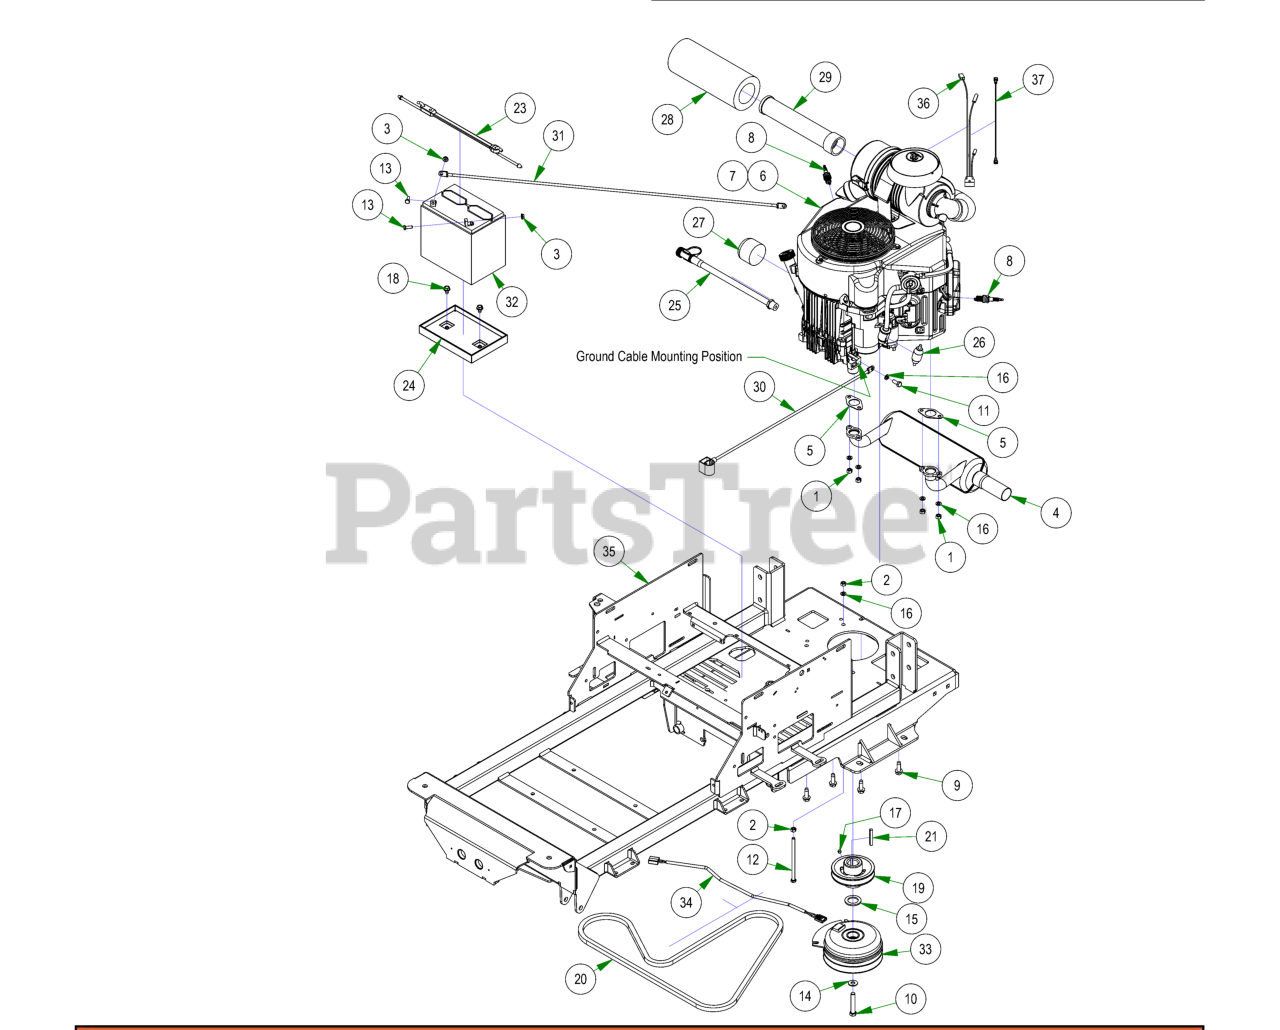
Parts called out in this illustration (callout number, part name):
1	M8-1.25 DIN 934 HEX NUT (CL.8) ZINC
2	5/16-18 HEX NUT ZINC
3	1/4-20 HEX SERRATED FLANGE NUT HARD/ZINC
4	Kawasaki Muffler 1251
5	Exhaust Gasket
6	FX691 Kawasaki-2016 Compact Outlaw
8	Spark Plug - Kawasaki
9	3/8-16 X 1-1/8 HEX WASHER UNSLOT SERRATED (TRI-LOB) TRS ZINC YELLOW
10	7/16-20 X 2-1/2 HEX Bolt GR 8 W/ Patch
11	M8-1.25 X 20MM DIN 933 HEX TAP BOLT (CL 8.8) ZINC
12	5/16-18 X 5-1/2 HEX CAP SCREW (GR.5) ZINC
13	1/4-20 X 3/4 HEX CAP SCREW (GR.5) ZINC
14	3/8 FLAT WASHER USS (1" OD) ZINC
15	1.140 ID X 1.750 OD X .132 THICK FLAT WASHER PLAIN
16	5/16 SPLIT LOCKWASHER ZINC
17	5/16-24 X 1/4 SOCKET SET SCREW (CUP PT) PLAIN
18	5/16-18 X 1/2 HWH unslot (F) tcs zinc
19	4 3/4 Motor Pulley
20	75.8" Pump Belt
21	1/4 X 2 SQ MACHINERY KEY 1018 STL PLAIN
22	2023 Battery Hold Down Assembly
23	2023 Rubber Battery Hold Down Strap
24	Battery Tray
25	Kawasaki Oil Drain
26	Universal Inline Fuel Filter
27	Oil Filter
28	Canister Air Filter- Outer
29	Canister Air Filter- Inner
30	24 inch Black Cable – MZ/ZT
31	36" Red Battery Cable
32	SP-35 Battery
33	Clutch Assembly
34	Clutch Pigtail
35	2023 Maverick Frame - Painted
36	Harness Adaptor
37	Compact Outlaw/Honda Starter Jumper Wire
